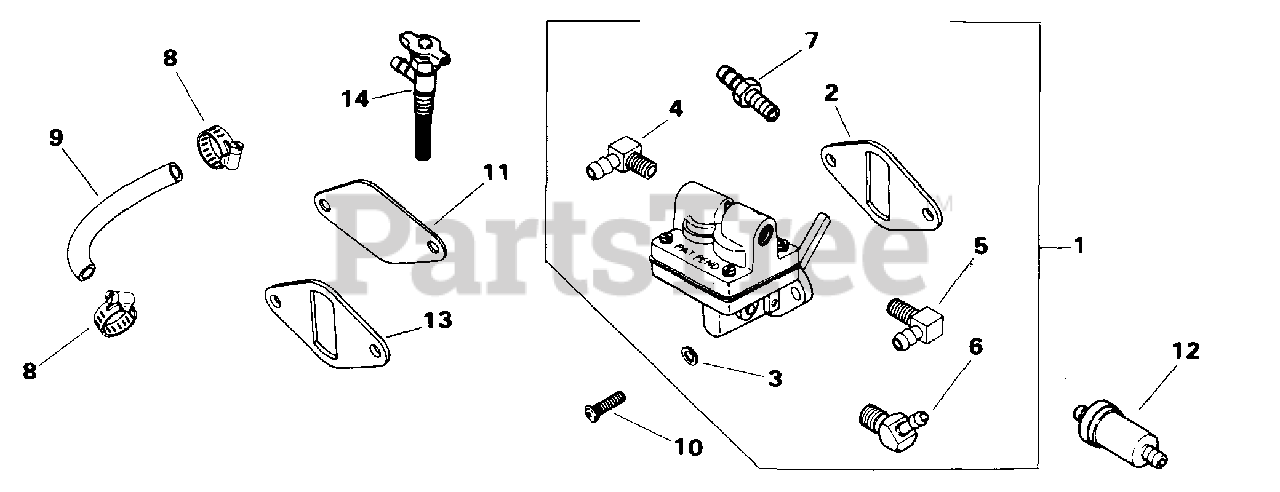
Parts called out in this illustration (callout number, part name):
3	WASHER, FLAT 1/4" (O.D. 1/2")
5	CONNECTOR, 90 DEG. HOSE
7	CONNECTOR USE 25 326 03-S
8	CLAMP, HOSE 1/2" USE 25 237 14-S
10	SCREW, POZ TRS HD 1/4-20X5/8" - DISCONTINUED
